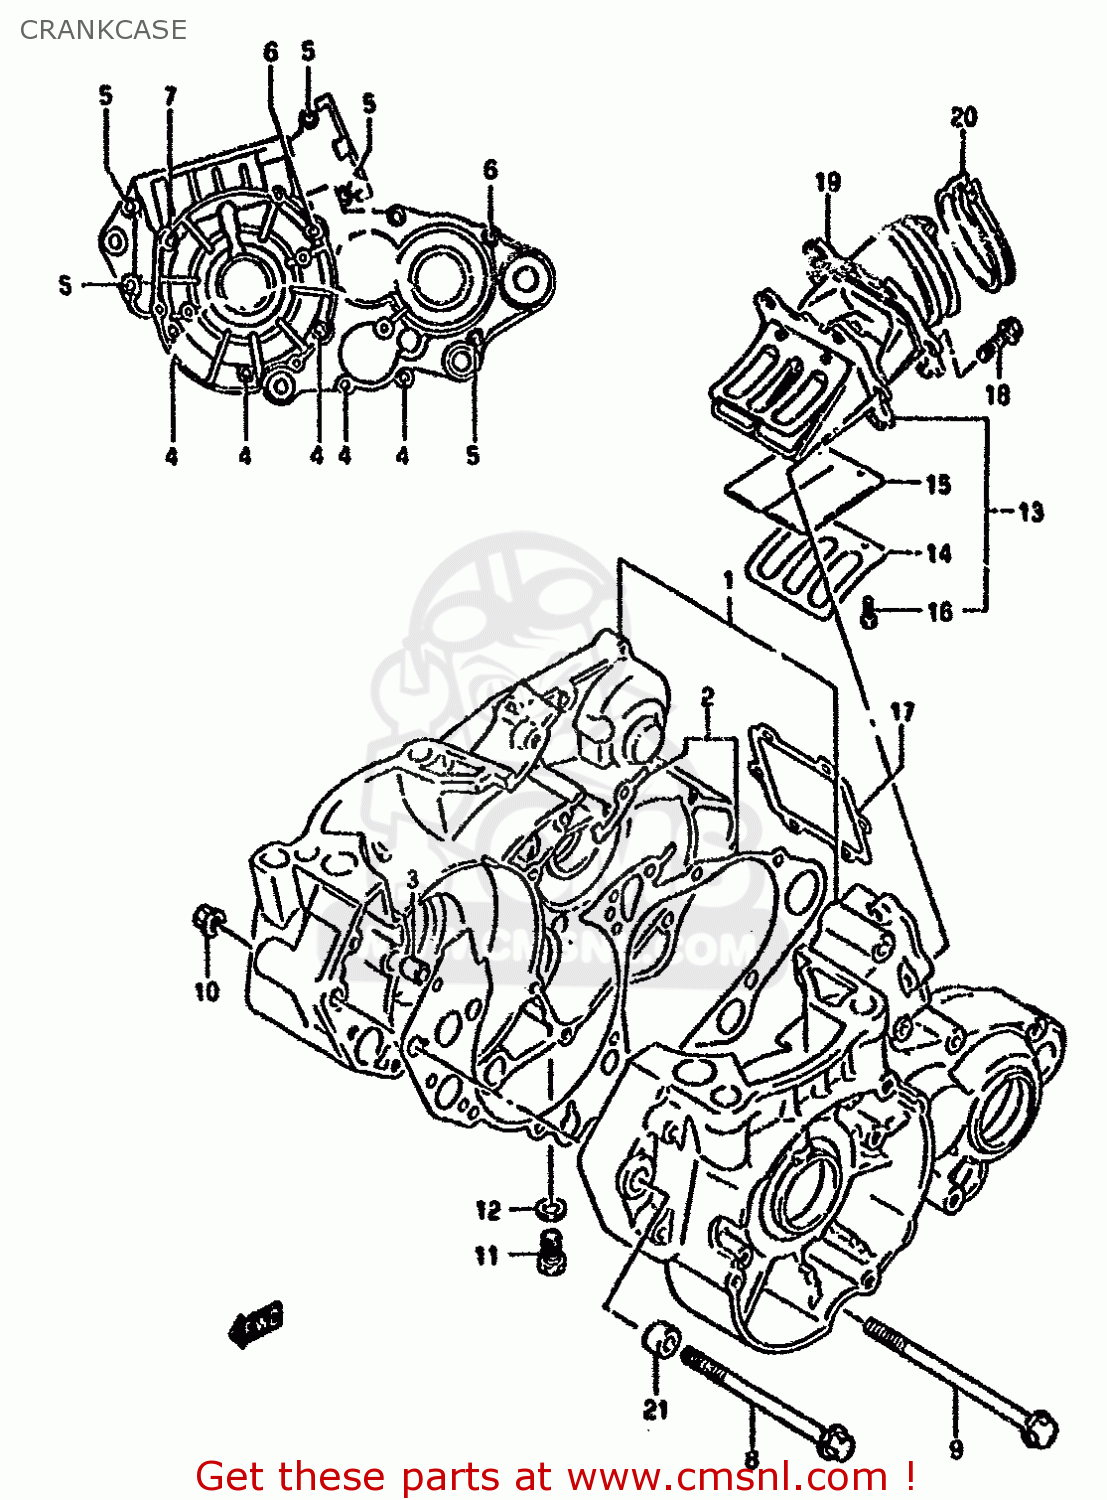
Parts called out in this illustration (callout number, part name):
1	CRANKCASE SET
2	GASKET,CRANKCASE (NAS)
3	PIN
4	BOLT
5	BOLT
6	BOLT
7	BOLT
8	BOLT(8X115)
9	BOLT(8X137)
10	NUT
11	BOLT
12	GASKET 8.2X14X1 (NAS)
13	VALVE ASSY,REED
14	STOPPER,REED VALVE
15	VALVE,REED
16	SCREW
17	GASKET,REED VALVE (NAS)
18	BOLT
19	PIPE,INTAKE
20	CLAMP
21	SPACER,ENG MTG
